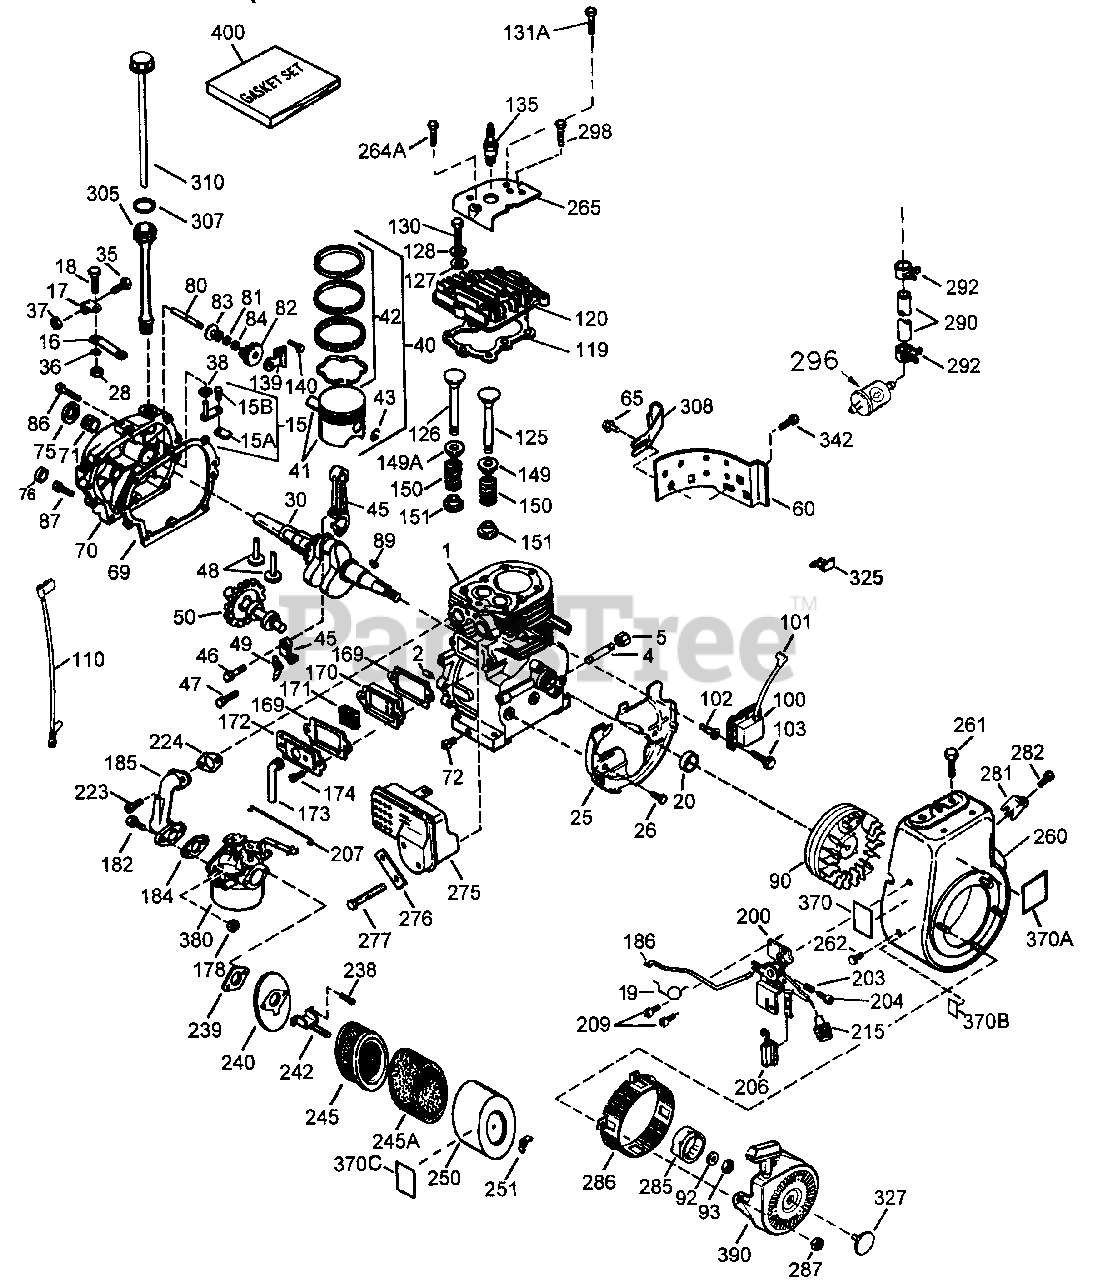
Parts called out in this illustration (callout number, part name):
1	Cylinder
2	Dowel Pin
4	Oil Drain Extension
5	Extension Cap
15	Governor Rod
15A	Governor Yoke
15B	Screw, 6-40 x 5/16"
16	Governor Lever
17	Governor Lever Clamp
18	Screw, 8-32 x 5/16"
19	Speed Control Spring
25	Blower Housing Baffle
26	Screw, 1/4-20 x 5/8"
28	Lock Nut, 8-32
30	Crankshaft
35	Screw, 10-32 x 3/4"
36	Lock Washer
37	Lock Nut, 10-32
38	Retaining Ring
40	Piston, Pin & Ring Set (Std.)
41	Piston & Pin Ass'y. (Std.)
42	Ring Set (Std.)
43	Piston Pin Retaining Ring
45	Connecting Rod Ass'y.
46	Connecting Rod Bolt
47	Connecting Rod Bolt
48	Valve Lifter
49	Oil Dipper
50	Camshaft (MCR)
60	Blower Housing Extension
65	Screw, 10-24 x 1/2"
69	Cylinder Cover Gasket
70	Cylinder Cover
71	Crankshaft Bushing
72	Oil Drain Plug
76	Camshaft Seal
80	Governor Shaft
82	Governor Gear Ass'y.
83	Governor Spool
84	Retaining Ring
86	Screw, 1/4-20 x 1-3/16"
87	Screw, 1/4-20 x 1-11/16"
89	Flywheel Key
92	Lock Washer
93	Flywheel Nut
100	Solid State Ignition
101	Spark Plug Cover
102	Solid State Mounting Stud
103	Screw, Torx T-15, 10-24 x 1"
110	Ground Wire
119	Cylinder Head Gasket
120	Cylinder Head
125	Exhaust Valve (Std.)
126	Intake Valve (Std.)
128	Belleville Washer
130	Screw, 5/16-18 x 2"
131A	Screw, 1/4-20 x 5/8"
135	Resistor Spark Plug
139	Governor Gear Bracket
140	Screw, 10-24 x 1/2"
149	Valve Spring Cap
149A	Valve Spring Cap
150	Valve Spring
151	Valve Spring Keeper
169	Breather Gasket
170	Breather Body
171	Breather Element
172	Valve Cover
173	Breather Tube
174	Screw, 10-24 x 1/2"
178	Nut & Lock Washer, 1/4-28
182	Screw, 1/4-28 x 1"
184	Carburetor
185	Intake Pipe
186	Governor Link
200	Control Bracket
203	Compression Spring
204	Screw, 5-40 x 7/16"
207	Throttle Link
209	Screw, 10-32 x 1/2"
215	Control Knob
223	Screw, Torx T-30, 5/16-18 x 1-1/8"
224	Intake Pipe Gasket
238	Screw, 10-32 x 1/2"
239	Air Cleaner Gasket
240	Air Cleaner Body
242	Air Cleaner Bracket
245	Air Cleaner Filter
245A	Air Cleaner Filter
250	Air Cleaner Cover
251	Wing Nut, 1/4-20
260	Blower Housing
261	Screw, 5/16-18 x 3/4"
262	Screw, Torx T-40, 5/16-24 x 21/32"
264A	Screw, 1/4-20 x 5/8"
265	Cylinder Head Cover
275	Muffler
276	Locking Plate
277	Screw, 5/16-18 x 3-3/16"
281	Starter Bubble Cover
282	Screw, 8-32 x 3/8"
285	Starter Cup
286	Starter Screen
287	Nut & Lock Washer, 1/4-28
290	Fuel Line
292	Fuel Line Clamp
296	Fuel Filter
298	Screw, 1/4-15 x 3/4"
305	Oil Fill Tube
308	Fill Tube Clip
325	Wire Clip
327	Starter Plug
342	Screw, Torx T-30, 1/4-20 x 1/2"
370	Instruction Decal
370A	Throttle Decal
370B	Logo Decal
370C	Instruction Decal
380	Carburetor
390	Rewind Starter
400	Gasket Set
